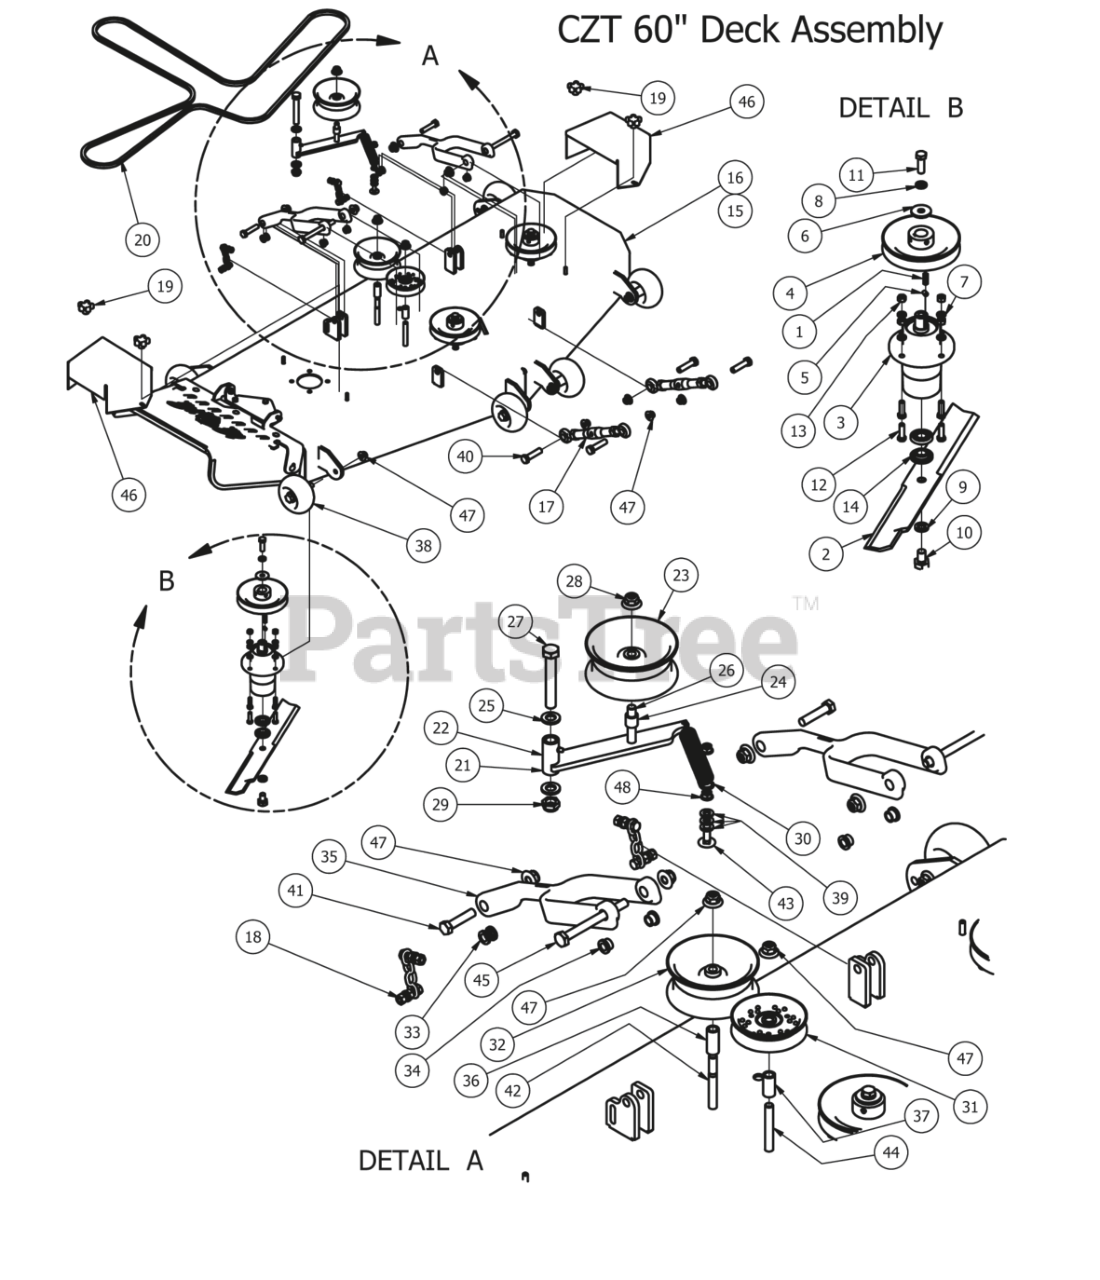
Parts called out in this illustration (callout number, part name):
1	1/4" x 1" Key
2	60 Inch Fusion Blade
3	Spindle-Aluminum - 2012
4	6 1/4" Drive Pulley
5	5/16 Set Screw
6	1/2 Belleville Washer
7	3/8" Lock Washer
8	1/2" Lock Washer
9	5/8" Lock Washer
10	5/8" x 1 1/2" Grade 8 Bolt
11	1/2"-20 x 1 1/2 - Grade 5 Fine Thread Bolt
12	3/8" x 1 1/4" Hex Bolt
13	3/8" Hex Nut
14	Spindle Bearing
15	60" ZT Deck Complete Assembly
16	60" ZT Deck
17	Turnbuckle (Top Link)
18	Chain assembly
19	5/16" Knob
20	60" ZT Deck Belt
21	Deck Idler Assembly components 22,23,24,26,28
22	Deck Idler Bracket
23	5 3/4" Deck Idler Pulley
24	3/4 OD x 1/2 ID x 3\4 Length
25	.635 ID Plastic Washer
26	1/2-13 x GR 5 Hex Bolt Zinc
27	5/8" x 4" Hex Bolt
28	1/2-13 Nylon Flange Nut-Orange
29	5/8" Nylock (1/2 Jam)
30	Deck Idler Spring 60" Deck only
31	4-3/4 Idler Pulley
32	5 3/4" Deck Idler Pulley
33	Flange for Lower Deck Arm
34	Flange Bushing For Deck Arm upper
35	Deck Arm Assembly
36	1 3/4" Pulley Spacer
37	Pup Pulley Spacer
38	Deck Wheel
39	3/8" Flat Washer
40	5/8" x 2 1/2" Hex Bolt
41	1/2-13X 2-1/4 GR Hex Bolts
42	1/2" x 4" Bolt (Grade 8)
43	3/8 x 1-1/2 Carriage Bolt
44	1/2 x 3 1/2 Flange Bolt Grade 8
45	1/2" x 5 1/2" Bolt
46	Pulley Cover
47	1/2-13 Nylon Flange Nut-Orange
48	3/8" Nylock Flange Nut
